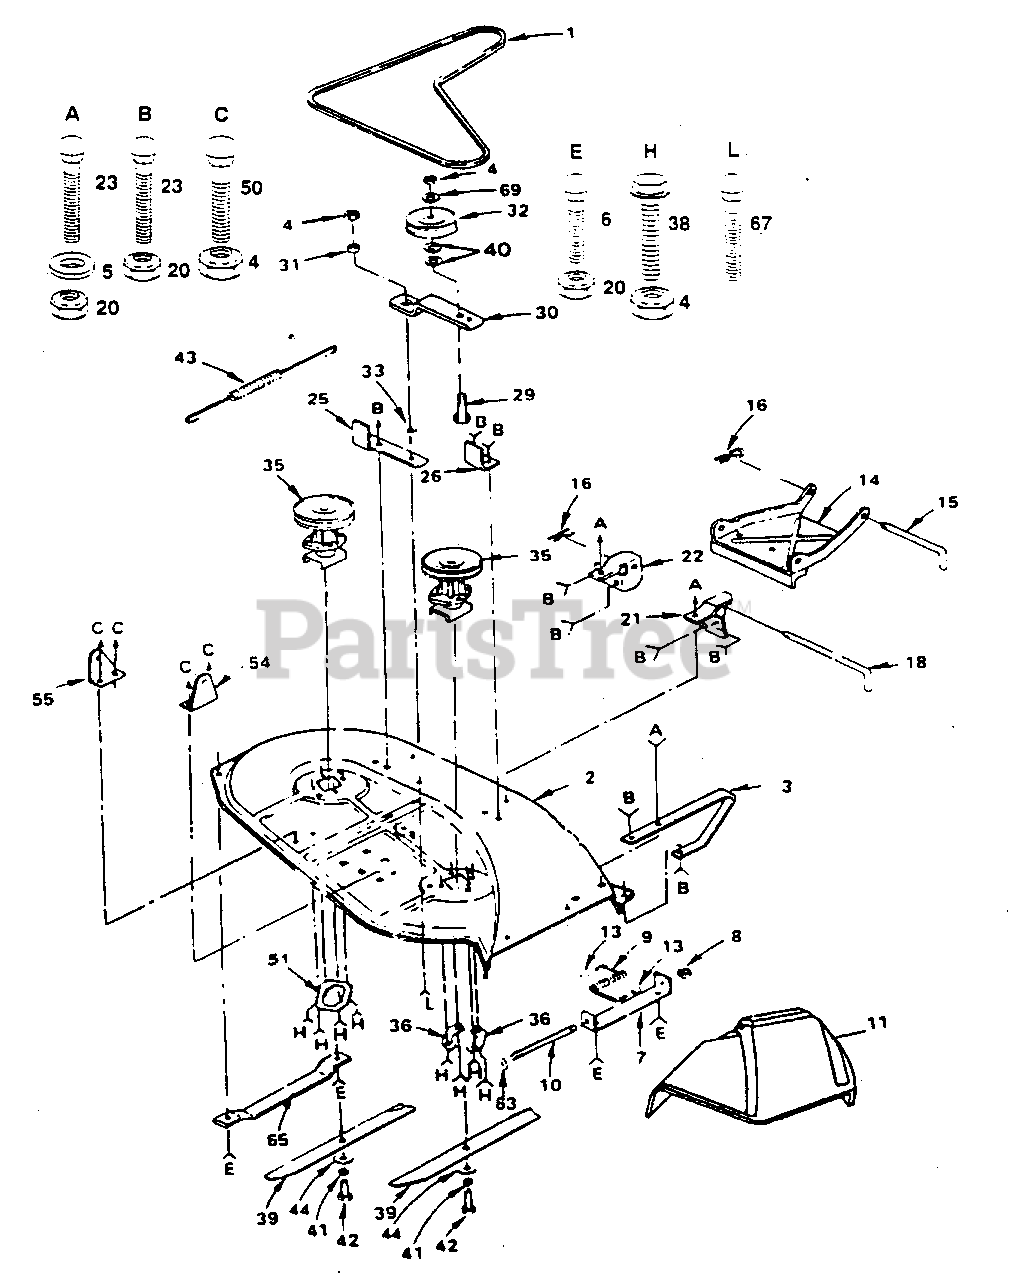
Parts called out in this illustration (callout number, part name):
1	Housing, Upper
2	Screw, Tapping, Lg. 1/4-20 x .734
4	Spring, Detent
6	Assembly, Shifter
8	Washer, Plain .505 x .942 x .006
8	Washer, Plain .505 x .942 x .010
8	Washer, Plain .505 x .942 x .015
8	Washer, Plain .505 x .942 x .020
8	Washer, Plain .505 x .942 x .026
8	Washer, Plain .505 x .942 x .030
8	Washer, Plain .505 x .942 x .040
9	Ring, Retaining
10	Ring, Retaining
11	Washer, Plain .632 x 1.00 x .010
11	Washer, Plain .632 x 1.00 x .020
11	Washer, Plain .632 x 1.00 x .026
11	Washer, Plain .632 x 1.00 x .031
11	Washer, Plain .632 x 1.00 x .036
11	Washer, Plain .632 x 1.00 x .041
11	Washer, Plain .632 x 1.00 x .046
11	Washer, Plain .632 x 1.00 x .050
11	Washer, Plain .632 x 1.00 x .060
11	Washer, Plain .632 x 1.00 x .082
13	Washer, Plain .632 x 1.38 x .046
14	Key, Woodruff #9
15	Assembly, Kit, Input Shaft
16	Pinion, Bevel, 14 Teeth
17	Ring, Retaining
18	Chain, 24 Pitches
19	Bearing, Flange
20	Gear, Spur, 14 Teeth
21	Collar, Clutch
23	Key, Woodruff
24	Shaft, Intermediate
25	Key, Woodruff #61
26	Ring, Retaining
27	Sprocket, 18 Teeth
29	Gear, Spur, 37 Teeth
30	Gear, Spur, 35 Teeth
31	Gear, Spur, 30 Teeth
32	Gear, Spur, 25 Teeth
33	Gear, Spur, 22 Teeth
34	Gear, Spur, 19 Teeth
35	Washer, Plain .640 x 1.37 x .061
36	Washer, Plain .632 x 1.00 x .026
37	Spacer .630 x 1.00 x .169
38	Assembly, Gear, Combination 12 Teeth and 35 Teeth
40	Spacer .635 x.875 x .755
41	Sprocket, 9 Teeth
42	Gear, Bevel, 42 Teeth
43	Washer, Plain .758 x 1.12 x .010
43	Washer, Plain .758 x 1.12 x .015
43	Washer, Plain .758 x 1.12 x .020
43	Washer, Plain .758 x 1.12 x .025
43	Washer, Plain .758 x 1.12 x .031
43	Washer, Plain .758 x 1.12 x .035
43	Washer, Plain .758 x 1.12 x .040
43	Washer, Plain .758 x 1.12 x .045
43	Washer, Plain .758 x 1.12 x .050
43	Washer, Plain .758 x 1.12 x .055
43	Washer, Plain .758 x 1.12 x .062
45	Gear, Spur, 12 Teeth
46	Gear, Spur, 15 Teeth
47	Gear, Spur, 20 Teeth
48	Gear, Spur, 25 Teeth
49	Gear, Spur, 28 Teeth
50	Gear, Spur, 31 Teeth
51	Washer, Plain .632 x 1.00 x .060
53	Washer, Plain .758 x 1.25 x .062
54	Axle, L.H.
55	Gear, Miter, 15 Teeth
56	Ring, Retaining
57	Gear, Spur, 32 Teeth
59	Gear, Miter, 15 Teeth
61	Housing, Lower
62	Puck, Friction
65	Jaw, Brake
67	Screw, Tapping, Lg. 5/16-18 x 2.25
68	Lever, Actuating
69	Washer, Plain .321 x 1.00 x .055
70	Bracket, Anti-Rotation
71	Locknut 5/16-24
72	Screw, Tapping, Lg. 5/16-18 x 1.44
73	Washer, Plain .343 x .81 x .059
74	Puck, Friction
75	Grease
